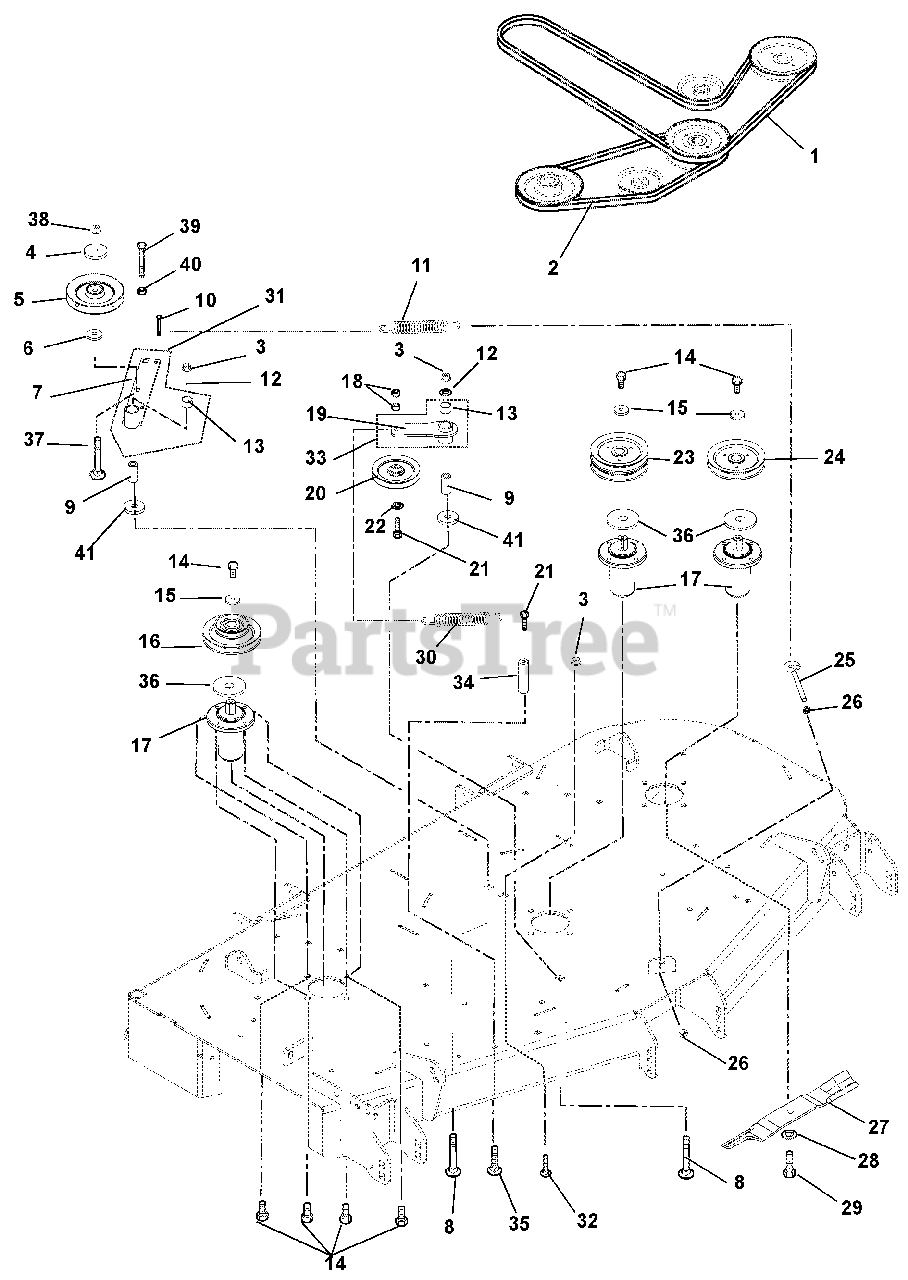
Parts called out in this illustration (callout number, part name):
1	Belt, 130" Long, PTO Drive Hex
2	V-Belt, 63" Long Cog B-Section
3	Nut, .50-13 Nyloc Flange
4	Cap, Idler Bearing Sealing
5	Sheave, .50"ID x 6.00"OD V-Idler
6	Bushing, Spacer .502 x .997 x .50
7	Idler, Pivot Arm
8	Bolt, Round Head Square Neck .50-13 x 3.50
9	Bushing, Spacer .505/.500 x .999/.996 x 2.05/2.03
10	Bolt, Shoulder .38-16 x .30 Hex
11	Spring, Extension
12	Washer, Flat Steel .563 x 1.38 x .109
13	Bushing, 1.00 x 1.125 x 1.936
14	Bolt, Hex .38-16 x 1.00
15	Washer, Flat Steel .406 x 1.50 x .245
16	Sheave, Double, 1" ID x 6.75" x 4.25" OD
17	Spindle Assembly
18	Nut, Locking Center .38-16
19	Idler, Pivot Arm
20	Assembly, V-Idler 5.00 O.D.
21	Bolt, Hex .38-16 x 2.25
22	Washer, Flat Steel .406 x .812 x .065
23	Pulley, Double 1" ID x 6.75" OD
24	Pulley, V-1" ID x 6.75" OD
25	Bolt, .38-16 x 5.50 .62 Diameter Eye
26	Nut, Hex Jam .375-16
27	Blade, Mower (20.50")
27	Blade, Mulching (20.50")
28	Washer, Bellville .63 x 1.625 x.14
29	Bolt, Hex .62-18 x 1.75 Grade 8
30	Spring, Extension
31	Assembly, PTO Idler Pivot Arm
32	Bolt, Round Head Square Neck .50-13 x 1.5, Full Thread, Grade 5
33	Assembly, Idler Pivot Arm
34	Nut, Coupling .375-16 x 1.75
35	Bolt, Round Head Square Neck .38-16 x 1.00
36	Retainer, Grease
37	Bolt, Round Head Square Neck .50-13 x 3.00 Grade 5
38	Nut, Locking Center .50-13
39	Bolt, Hex .38-16 x 2.75 Grade 5
40	Nut, Hex .38-16
41	Washer, Flat .640 x1.75 x.25
